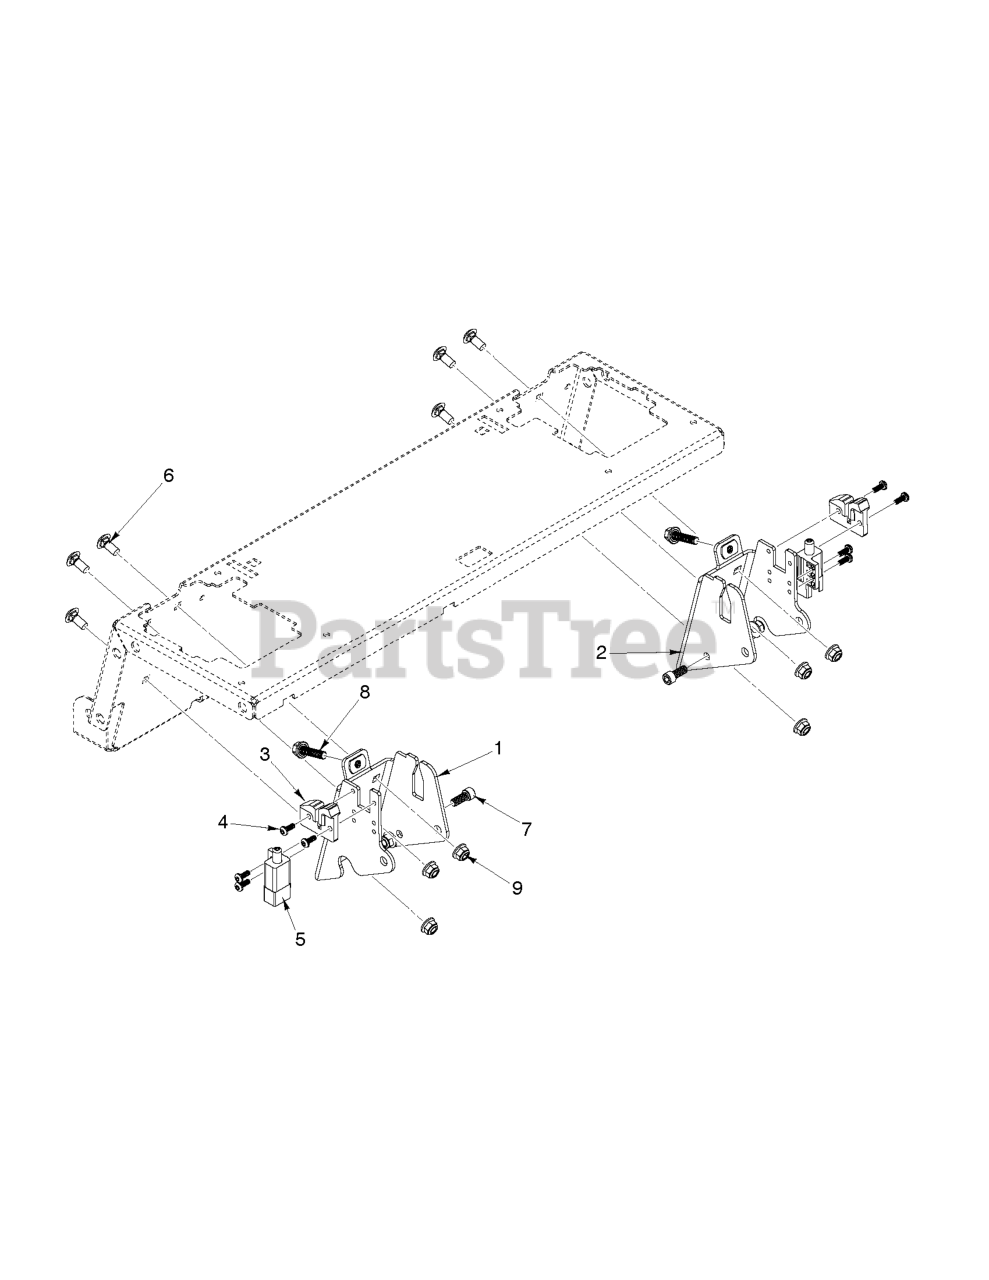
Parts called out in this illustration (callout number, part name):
1	Brackets
2	Brackets
3	Guides
4	Screws
5	SWITCH.INTLK.RZ.RFRSH.BUTTON
6	GSPW Bolts
7	Screws
8	SCREW.SHAKEPROOF.1.25.BLACK
9	NUT HEXAGON FLANGE 5/16-18 ST
